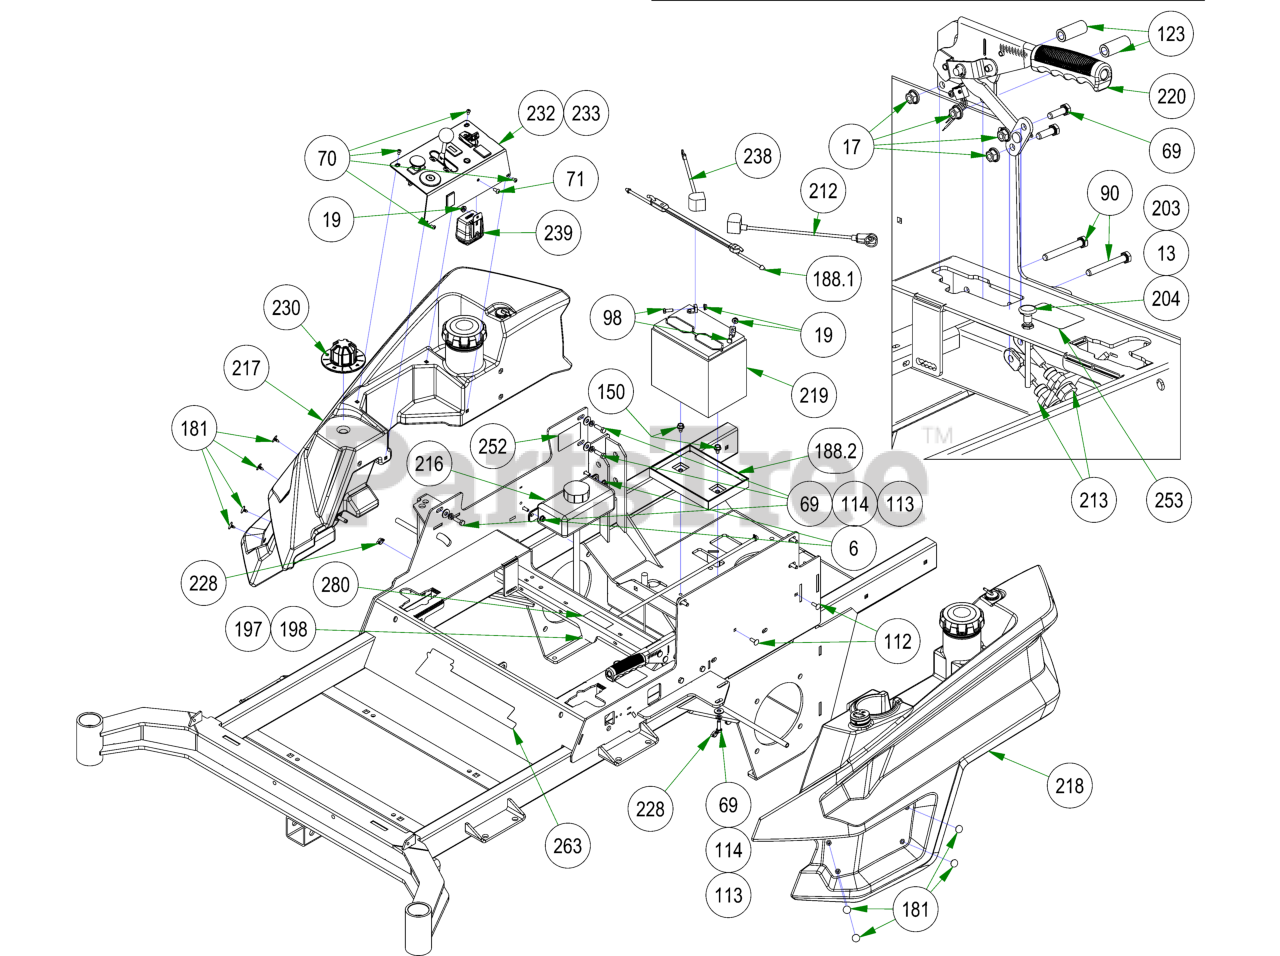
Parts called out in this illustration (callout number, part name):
6	1/4-20 NYL INSERT FLANGE LOCKNUT ZINC
13	3/8-24 HEX NUT ZINC YELLOW
17	5/16-18 NYLON INSERT FLANGE LOCKNUT ZINC
19	1/4-20 HEX SERRATED FLANGE NUT HARD/ZINC
69	5/16-18 X 1 HEX CAP SCREW (GR.5) ZINC
70	10-32 X 3/8 BUTTON SOCKET CAP SCREW 18-8 STAINLESS STEEL
71	1/4-20 X 1/2 BUTTON SOCKET CAP SCREW 18-8 STAINLESS
90	5/16-18 X 2-1/2 HEX CAP SCREW (GR.5) ZINC
98	1/4-20 X 3/4 HEX CAP SCREW (GR.5) ZINC
112	1/4-20 X 3/4 CARRIAGE BOLT (GR.5) ZINC
113	5/16 USS FLAT WASHER (7/8 OD) ZINC
114	5/16 SPLIT LOCKWASHER ZINC
122	MZ Deck Idler Spacer
123	.380 ID X .625 OD X 1.500 LGTH 2019 OUTLAW BRAKE HANDLE
150	5/16-18 X 1/2 HWH unslot (F) tcs zinc
181	3/16 x .48 Christmas Tree Nylon Black
188	2023 Battery Hold Down Assembly Strap
188.1	2023 Rubber Battery Hold Down Strap
188.2	Battery Tray
197	2023 Rebel Rogue Renegade Fuel Line for Kohler
198	2023 Rebel Rogue Renegade Fuel Line for Kawasaki
204	Choke for 36Hp Vanguard & FX1000 Kawasaki
212	14" Red Battery Cable-Base Outlaw
213	Long Brake Cable
216	2019 Rebel Hydro Tank Assembly
217	2019 Right Rebel, Rogue, Renagade Fuel Tank (GAS)
218	2019 Left Rebel, Rogue, Renegade Fuel Tank (GAS)
219	SP-35 Battery
220	2019 Brake Handle Assembly
224	2023 Rebel Frame - Painted
228	2 EAR CLAMP 12.5mm-15mm
230	2019 Rigid Deck Dial 1.5 to 5.5
232	Rebel/Rogue Control Panel Assy
232.9	2022 Rebel Control Panel
238	Starter Cable
239	2019 Wiring Harness-Rebel/Rogue
252	Hydraulic Decal
253	2018 Out/XP/Diesel Brake Decal
263	2019 Rebel Cooler Cover Decal
280	R-Series Shut Off Valve Decal
